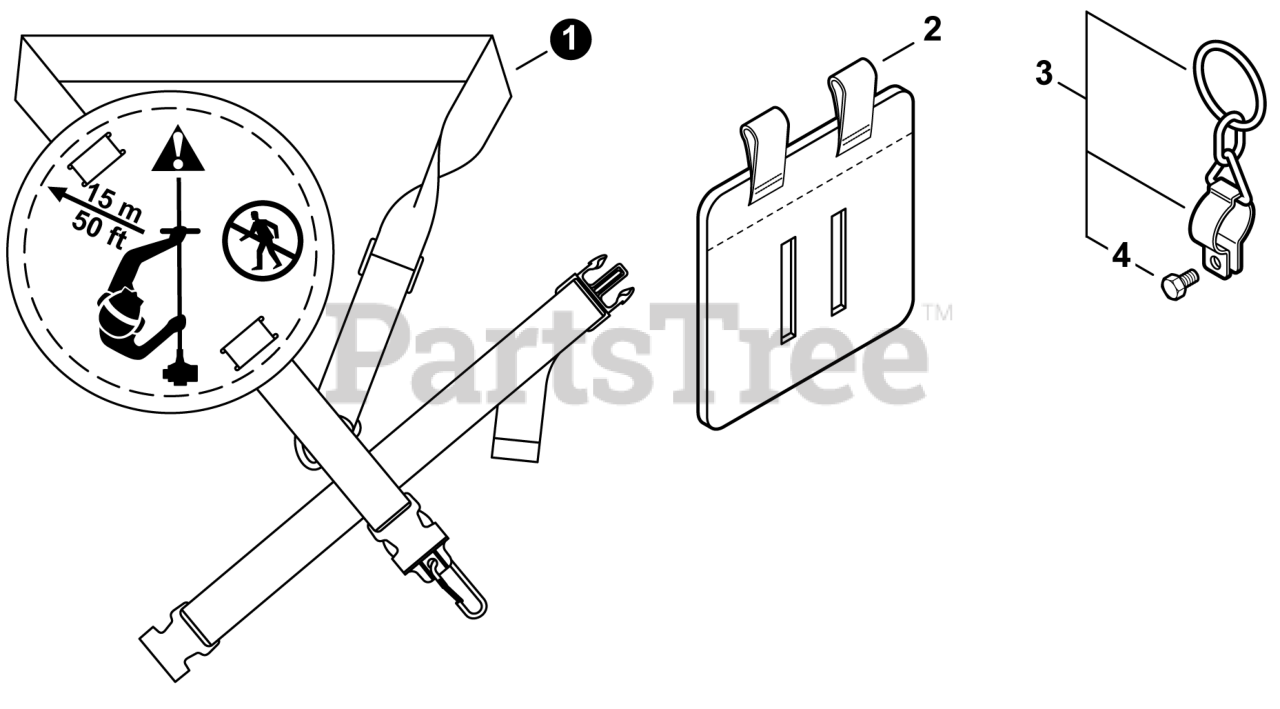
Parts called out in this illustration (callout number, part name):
1	HARNESS, SHOULDER
2	PAD, HIP
3	HANGER SET, HARNESS
4	BOLT, TORX 5x12
